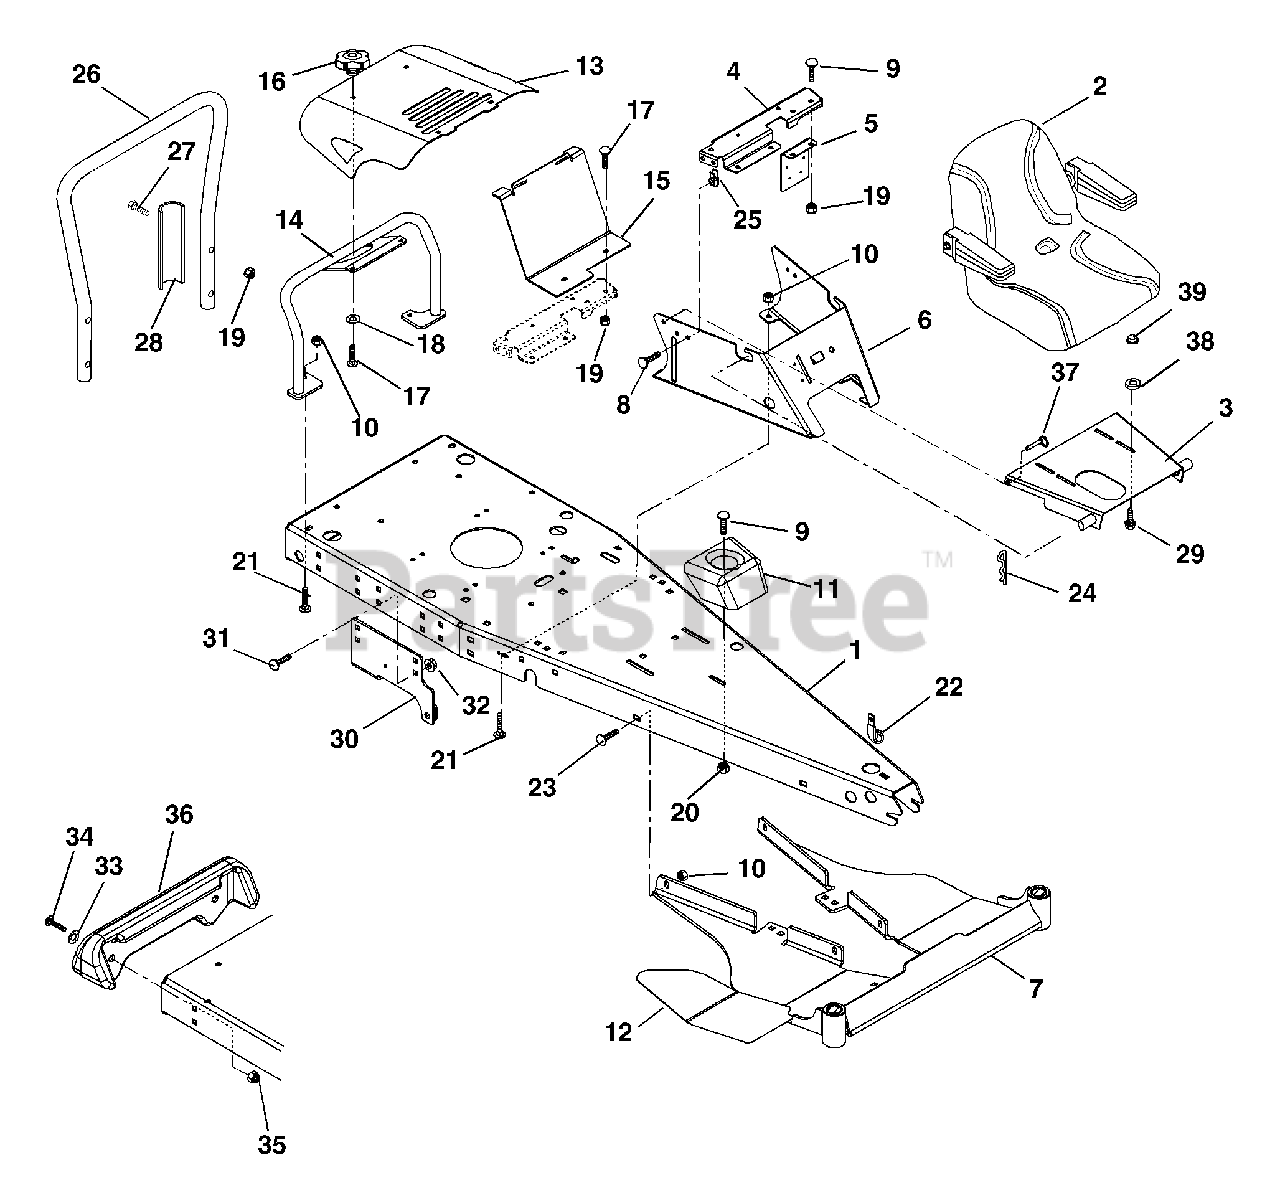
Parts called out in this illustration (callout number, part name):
1	FRAME,RER/SPORT-ZOOM
2	SEAT, TS2500 MICHIGAN W/ARM.
3	WLDM'T, SEAT PLATE
4	REINFORCEMENT, SEAT SUPPORT
5	PANEL-SOLENOID MOUNTING
6	SEAT SUPPORT
7	REST, RER/SZ FOOT
8	BLT-SERHFWH .25-20X.75 YWZC
9	BLT-RDHDSQNK .31-18X.75 G5BZ
10	NUT-LK-TOP-FLG .38-16 BLKZC
11	CUP HOLDER RER
12	GRIP, LEFT FOOT REST
12	GRIP, RH FOOT REST
13	ENGINE-HOOD ARIENS
14	WLDM'T TUBE
15	BRACKET-HOOD SUPPORT
16	KNOB-CLAMPING, .312-18 NYLOC
17	BLT-RDHDSQNK .31-18X1.0 SHTYZ
18	NUT-PUSH .312
19	NUT-LK-TOP-FLG .31-18 BLKZC
20	@NUT-SPNLK-FLG .312-18 YWZC
21	BLT-RDHDSQNK .38-16X.75 G5BZ
22	J-CLAMP
23	BLT-RDHDSQNK .38-16X1.00 G5BZ
24	PIN-HAIR-EXT .12X.31X2.37 YWZC
25	NUT-RTNR .25-20X.56
26	TUBE
27	@BLT-HEX .31-18X1.50 GR5 YWZC
28	BRACE
29	BLT-SERHFWH .31-18 X 1 YWZC
30	BRKT, TRANS (RH-WLDMNT)
30	BRKT, TRANS (LH-WLDMNT)
31	BLT-RDHDSQNK .38-16X.75 G5BZ
32	NUT-LK-TOP-FLG .38-16 BLKZC
33	@WSHR-FL-STL.438X1.00X.083 YWZ
34	@BLT-HEX .38-16X1.75 GR5 YWZC
35	NUT-LK-TOP-FLG .38-16 BLKZC
36	WEIGHT, SPORT-Z
37	PIN-DET W/RING .25X1.00
38	SPACER, .344X1.00X.410
39	NUT-PUSH .312
